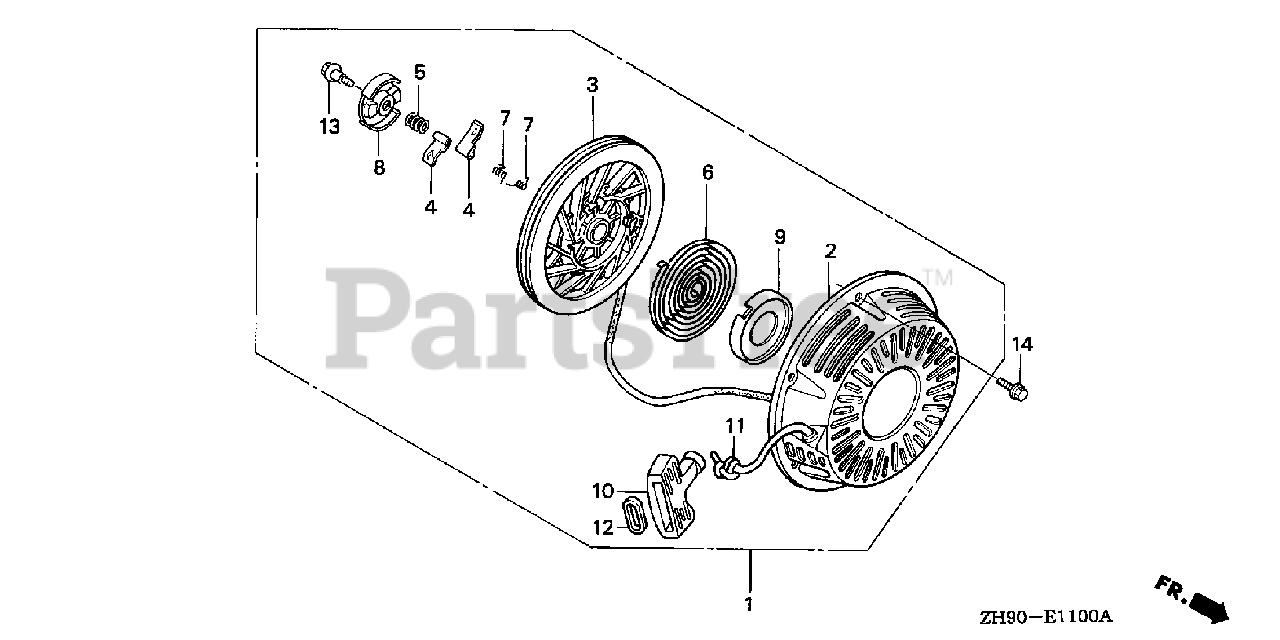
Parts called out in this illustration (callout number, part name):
1	STARTER ASSY., RECOIL *R8* (BRIGHT RED)
2	CASE, RECOIL STARTER *R8* (BRIGHT RED)
3	PULLEY, RECOIL STARTER
4	RATCHET, STARTER
5	SPRING, FRICTION
6	SPRING, STARTER RETURN
7	SPRING, RATCHET
8	RETAINER, SPRING
10	GRIP, STARTER
11	ROPE, RECOIL STARTER
13	SCREW, CENTER
14	BOLT, FLANGE (6X10)
